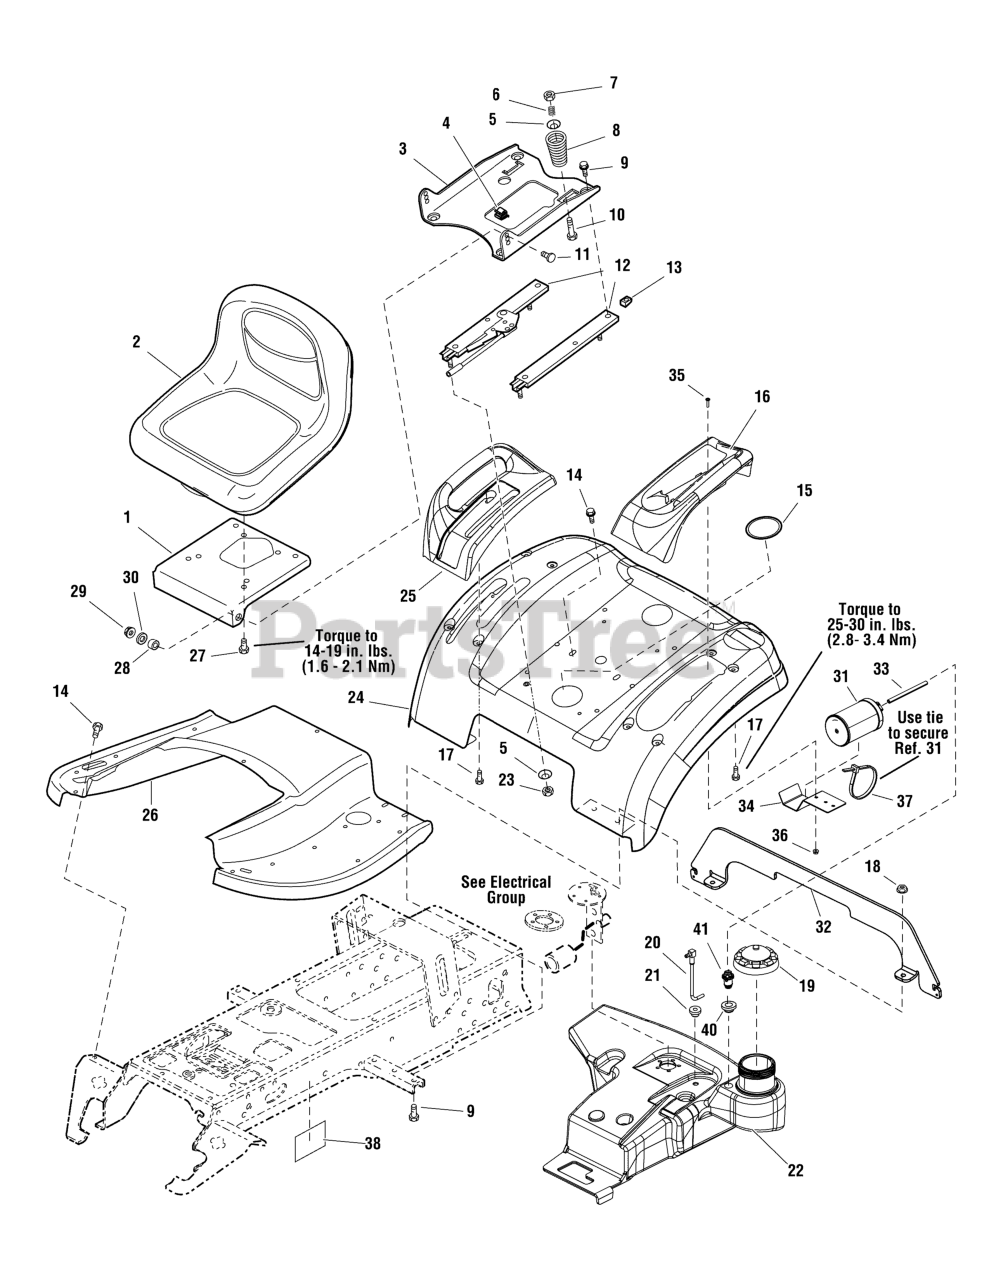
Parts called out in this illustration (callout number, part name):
1	BRACKET, 1-5/8 x 1-3/4
2	SEAT, 18"
3	SUPPORT, Seat
4	CLIP, Wire
5	WASHER, Spring, 5/16 x 1 1/4
6	SPRING, Compression
7	NUT, Hex Lock, ESNA Light, 5/16-18
8	SPRING, Compression
9	CAPSCREW, Hex Flange Whiz Lock, 5/16-18 x 3/4
10	BOLT, Carriage, 5/16-18 x 2
11	BOLT, Carriage, 3/8-16 x 1
12	SLIDE, Seat
13	NUT, Speed, Lug Type, 5/16-18
14	CAPSCREW, Hex Washer Head Taptite, 5/16-18 x 5/8
15	PLUG, Plastic
16	POD, with Cup Holder, LH
17	SCREW, Conical Washer, 1/4-20 x 7/8 Dog Point
18	NUT, Hex Flange Whiz Lock, 5/16-18
19	CAP, Gas
20	TUBE & ELBOW ASSEMBLY
21	BUSHING, 3/8 x 9/16 x 5/8, Rubber
22	TANK, Fuel
23	NUT, Hex KEPS, 5/16-18
24	DECK, Seat
25	POD, RH with 2 Slots
27	CAPSCREW, Hex Flange Whiz Lock, 5/16-18 x 1
28	SPACER, 25/64 x 5/8 x 3/16
29	NUT, Hex Flange Two-Way Lock, 3/8-16
30	WASHER, 3/8
31	CARBON CANISTER, 300CC
32	SUPPORT, Mower Hanger
33	HOSE, Vapor
34	BRACKET, Canister Mounting
35	SCREW, Round Head Phillips, #10-24 x 3/4
36	NUT, KEPS Lock, #10-24
37	TIE, Self Locking
38	DECAL, EVAP
40	GROMMET
41	REMOTE VENT ASSEMBLY
